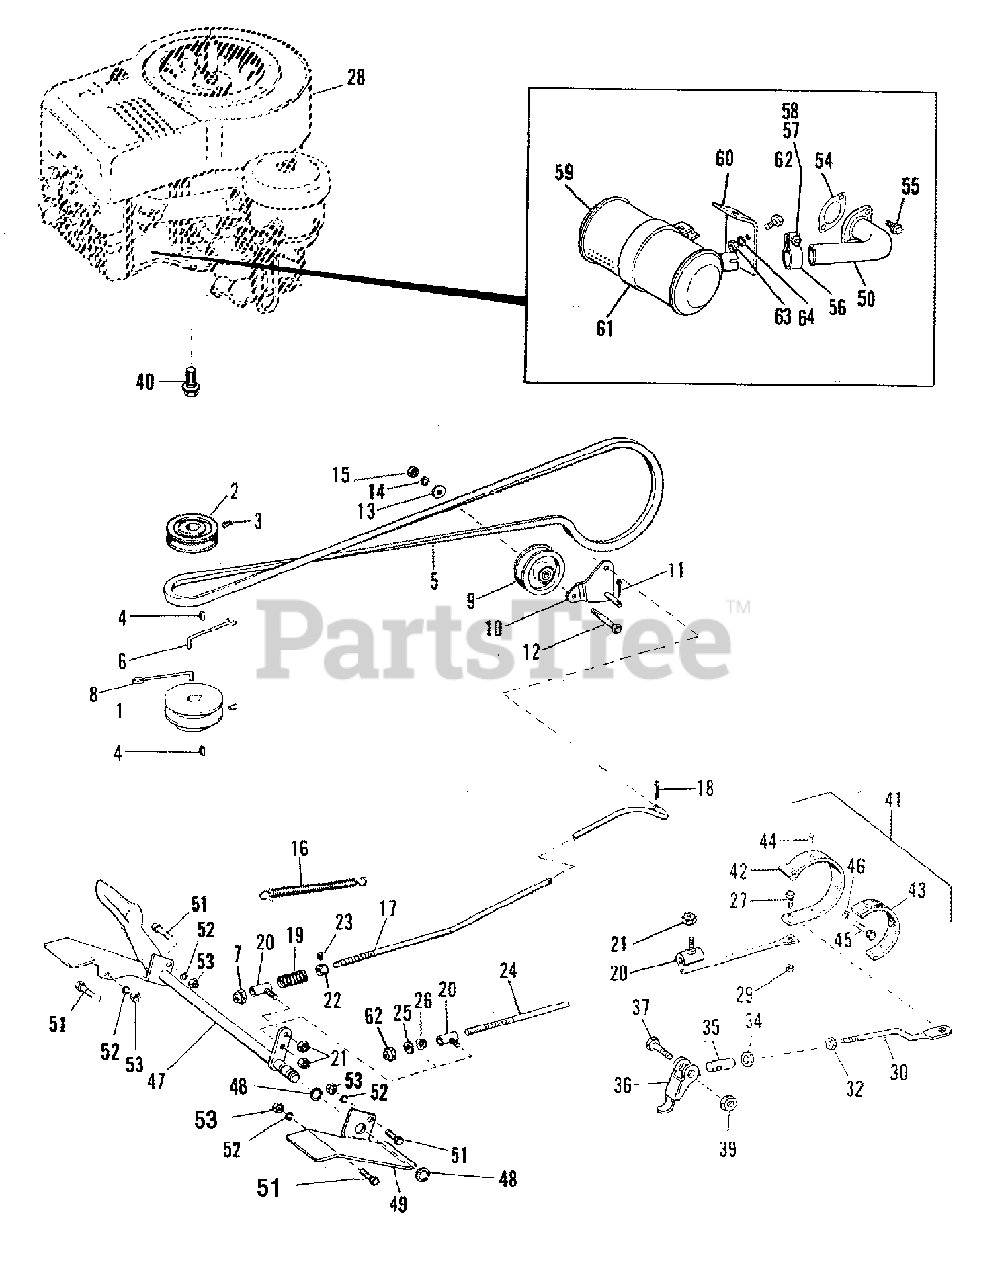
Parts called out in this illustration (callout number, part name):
1	PULLEY, Engine Large
3	SETSCREW, 5/16-18 x 5/16" Large
5	BELT, "V" Drive
6	STOP, Belt
7	WASHER, Plain
8	STOP, Belt
9	PULLEY, Idler
10	BRACKET ASSEMBLY, Pulely
11	PIN, Cotter, 1/8" x 3/4"
12	CAPSCREW, Hex, 3/8" 16 x 1-1/4" Large
13	WASHER, Plain, 5/16"
14	LOCKWASHER, 3/8"
15	NUT, Full, Hex, 3/8"-16
16	SPRING, Return
17	ROD, Clutch, P.T.O.
18	PIN, Cotter, 1/8" x 3/4" Large
19	SPRING, Compression
20	GUIDE ASSEMBLY, Guide
21	LOCKNUT, Full, Hex 5/16"-18
22	COLLAR, Set
23	SETSCREW, 1/4"-20 x 3/8" Large
24	ROD, Brake
25	WASHER, Plain, 3/8" Large
26	SPRING, Conical
27	CAPSCREW, Hex, 1/4"-20 x 3/4" Large
28	ENGINE, 8 H.P.
29	LOCKNUT, Full, Hex, 1/4"-20
30	ROD, Parking Brake
32	NUT, Full, Hex 5/16-18
34	WASHER, Plain, 1/2"
36	LEVER, Parking Brake
37	CAPSCREW, Hex, 1/4"-20 X 1-1/4" Large
39	LOCKNUT, Full, Hex, 1/4"-20
40	CAPSCREW, Hex, Special, 3/8"-16 X 1-1/4" Large
41	BAND ASSEMBLY, Brake
42	CAPSCREW, Hex, 3/8"-16 x 1-1/2" Large
43	LOCKWASHER, 3/8"
44	SHAFT ASSEMBLY, Clutch
45	RING "E"
46	FOOT REST, L.H.
47	NUT, Elastic Stop, 5/16-18
48	CAPSCREW, Hex, 3/8" 16 x 3/4" Large
49	LOCKWASHER, 3/8"
52	NUT, Full, Hex, 3/8"-16
55	SCREW, Hex, Whizlock, 5/16-18 x 3/4
57	SCREW, Hex. Head, 5/16-18 x 1-1/4
58	NUT, Hex, Full, 5/16-18
62	SCREW, Hex Taptite, 5/16-18 x 1
63	LOCKNUT, Hex, 5/16-18
64	LOCKWASHER, 5/16
